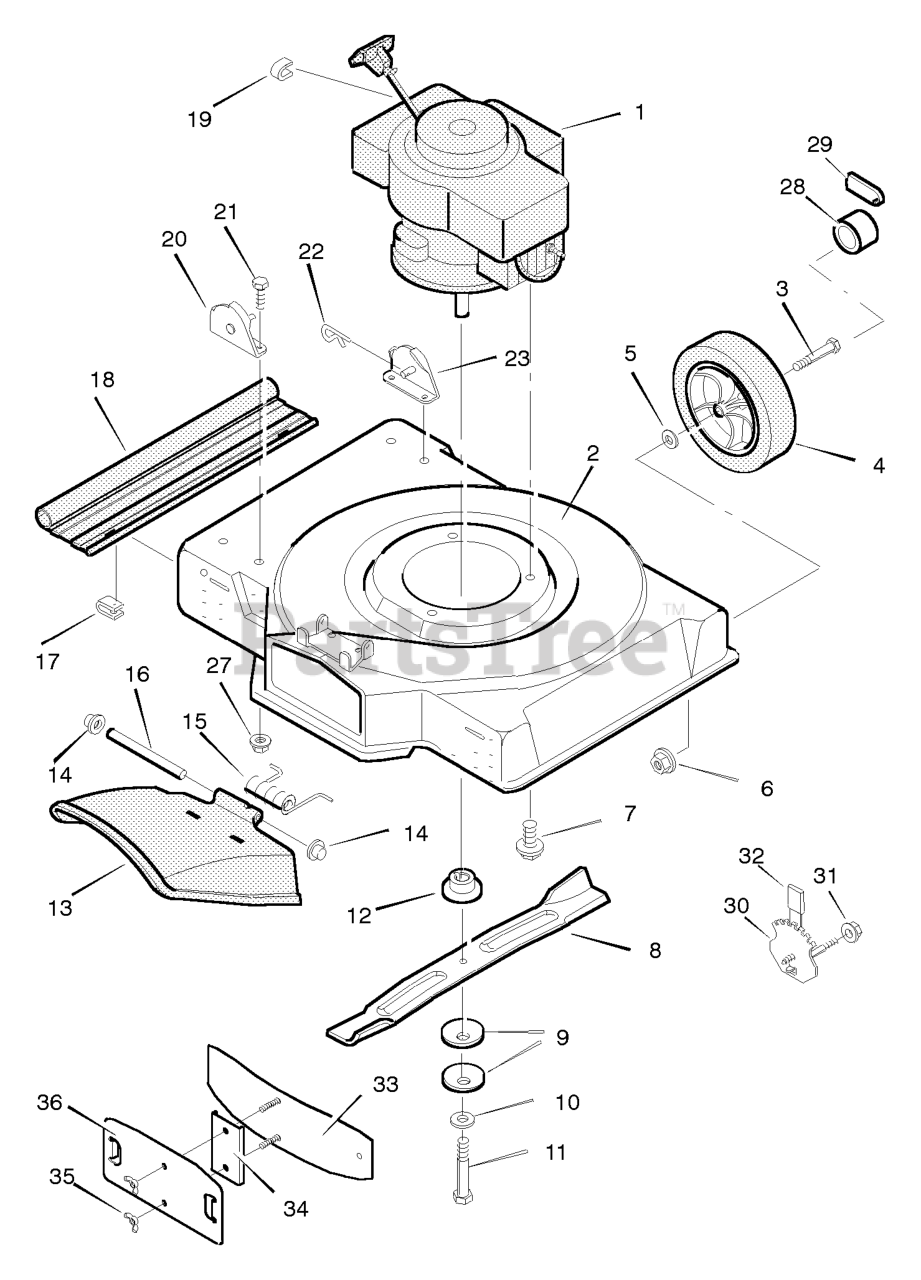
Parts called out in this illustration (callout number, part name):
1	Engine *
2	Housing
3	Bolt, Axle
4	Wheel and Tire *
6	Locknut, Flange
7	Bolt, Engine
9	Washer, Belleville
11	Bolt, Hex
12	Adapter, Blade
13	Deflector, Chute
14	Push- On Cap
16	Pin, Pivot
17	Retainer
18	Deflector, Rear
19	Stop, Rope
20	Bracket, Right Handle
22	Pin, Hair
23	Bracket, Left Handle
27	Nut
28	Hub Cap
29	Hub Cap
30	Adjuster, Height
31	Locknut, Flange
33	Baffle Assembly
34	Spacer
35	Wingnut
36	Cover
